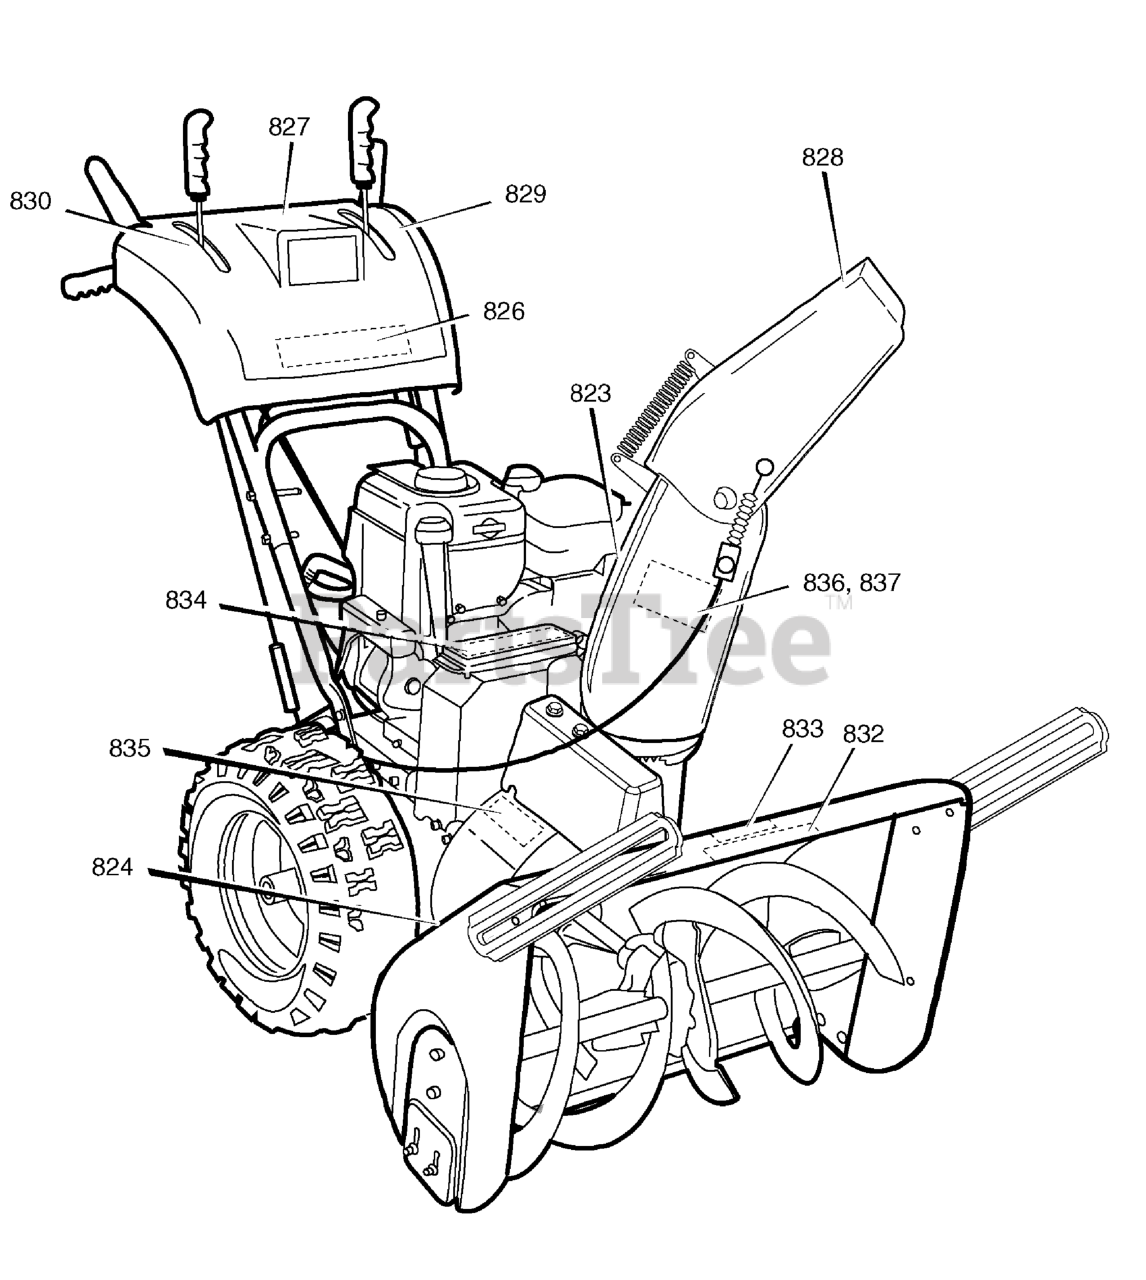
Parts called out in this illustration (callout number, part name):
823	DECAL, DANGER CHUTE HAND
824	DECAL, DANGER FOOT
826	DECAL, CRAFTSMAN
827	DECAL, SINGLE HAND CONTROL
828	DECAL, THROWN OBJECTS
829	DECAL, REMOTE CHUTE ELECTRIC
830	DECAL, TRANS 1550/30 (FR/EN)
832	DECAL, CRAFTSMAN 1550/30 (FR/EN)
833	DECAL, CLEAN & CLEAR BRUSH
834	DECAL, TOOLBOX INFORMATION
835	DECAL, PINCH POINT ELECTRIC
836	DECAL, POWER 2 STEER, ENGLISH
837	DECAL, POWER 2 STEER, FRENCH
